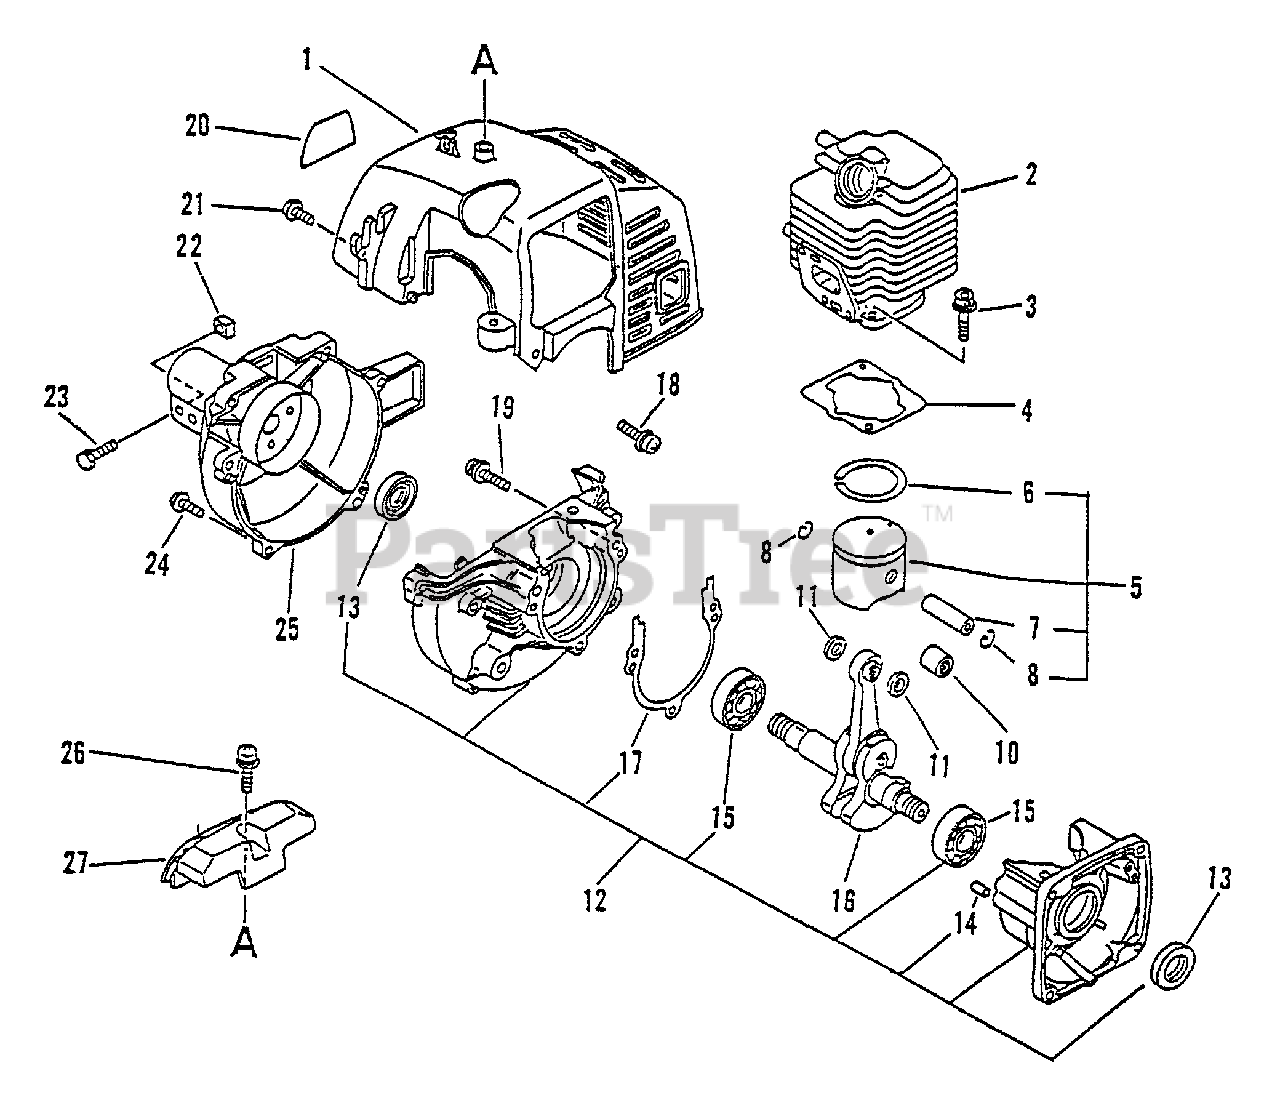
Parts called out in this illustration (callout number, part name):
1	COVER, ENGINE - GRAY
2	CYLINDER
3	BOLT 5×22
4	GASKET, CYLINDER
5	PISTON KIT
6	RING, PISTON
7	PIN, PISTON 8
8	RING, SNAP
10	BEARING, NEEDLE
11	WASHER, THRUST
12	CRANKCASE KIT
13	SEAL, OIL 12
14	PIN, LOCATING 4
15	BEARING, BALL - 6201 C3
16	CRANKSHAFT ASSY
17	GASKET, CRANKCASE
18	SCREW 4×12
19	SCREW 5×28
20	LABEL - MODEL
21	SCREW 4×16
22	NUT M5
23	BOLT 5×28
24	SCREW 4×18
25	FAN CASE ASSY
26	SCREW 5×16
27	GUARD, TOP - BLACK
